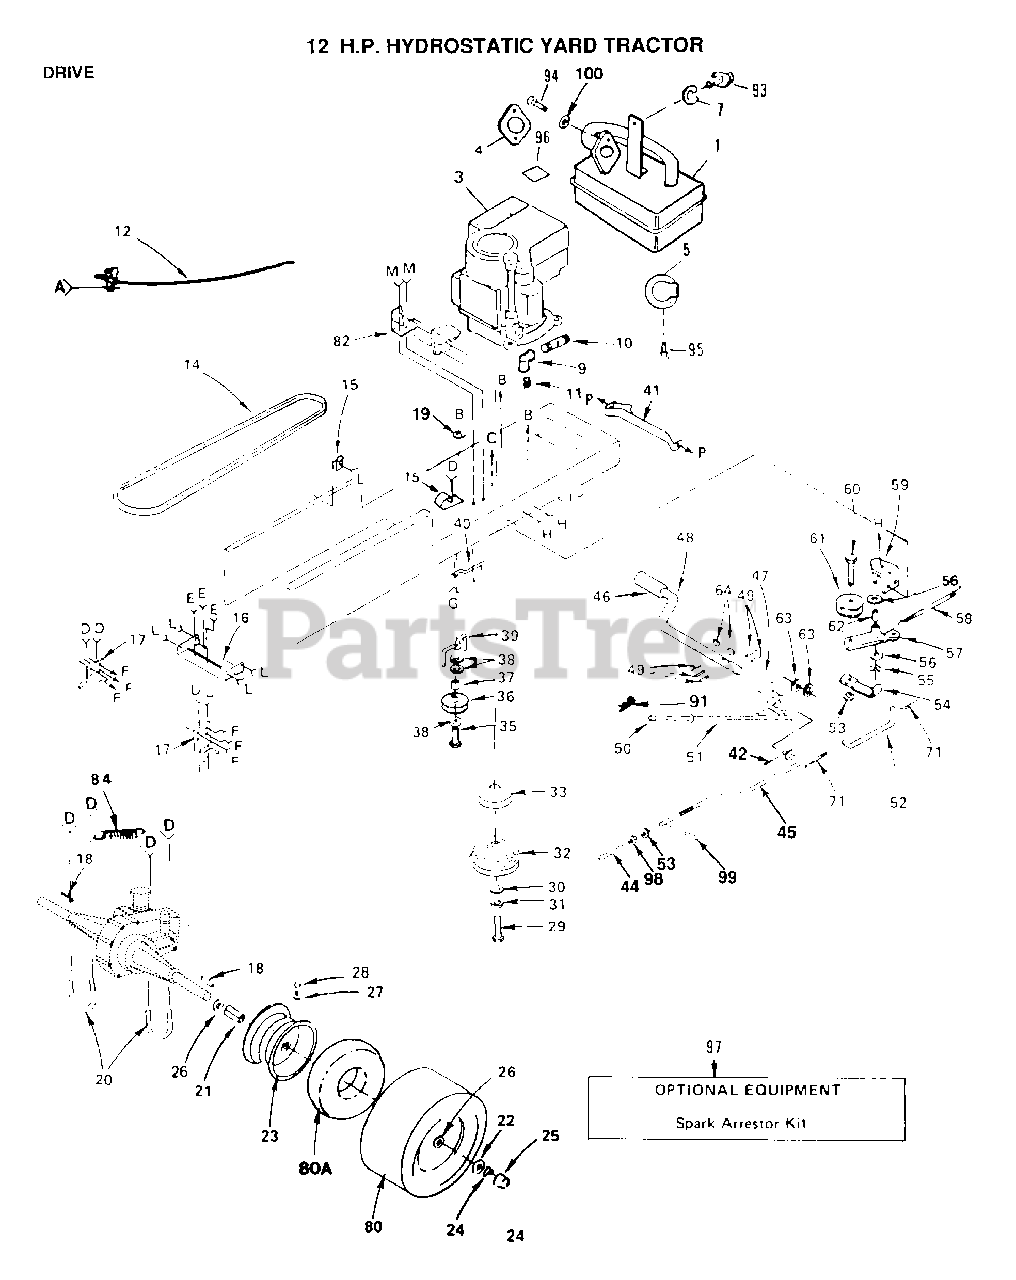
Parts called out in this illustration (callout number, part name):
1	MUFFLER LT
3	ENGINE 12 H.P. TYPE 0201-01
5	DEFLECTOR.222573
7	LOCKWASHER
9	ELBOW
10	NIPPLE PIPE LT
11	PLUG OIL DRAIN
15	CLIP T
16	PLATE TRANS SUPT
19	NUT
20	U BOLT
21	SPACER SPLIT
22	WASHER
24	E-RING LT
25	HUB CAP
27	VALVE STEM LT
28	VALVE CAP
30	WASHER LT
31	LOCKWASHER
35	BOLT
37	SPACER T
38	WASHER
39	"KEEPER,BLT ENG LT"
40	KEEPER BELT ENGLH
42	COTTER PIN
44	SPRING ROD LT
45	ROD BRAKE
46	PEDAL COVER T
47	ARM BRAKE LT
48	FOOT SHAFT PEDAL
50	PLUNGER CAP T
52	"LINK, CLUTCH T"
55	KLIP RING
56	WASHER LT
57	"ASS T, BELLCRAN"
58	"SPRING, RETURN LT"
62	"LY, BEARING"
63	WASHER
71	COTTER PIN
80A	TUBE.18X9.5-8
82	BRACKET LT
91	SPRING.RETAINER
93	BOLT
94	SCREW LT
95	SCREW LT
96	DECAL.ENG.271967
98	NUT
99	RETAINER M
100	LOCKWASHER
